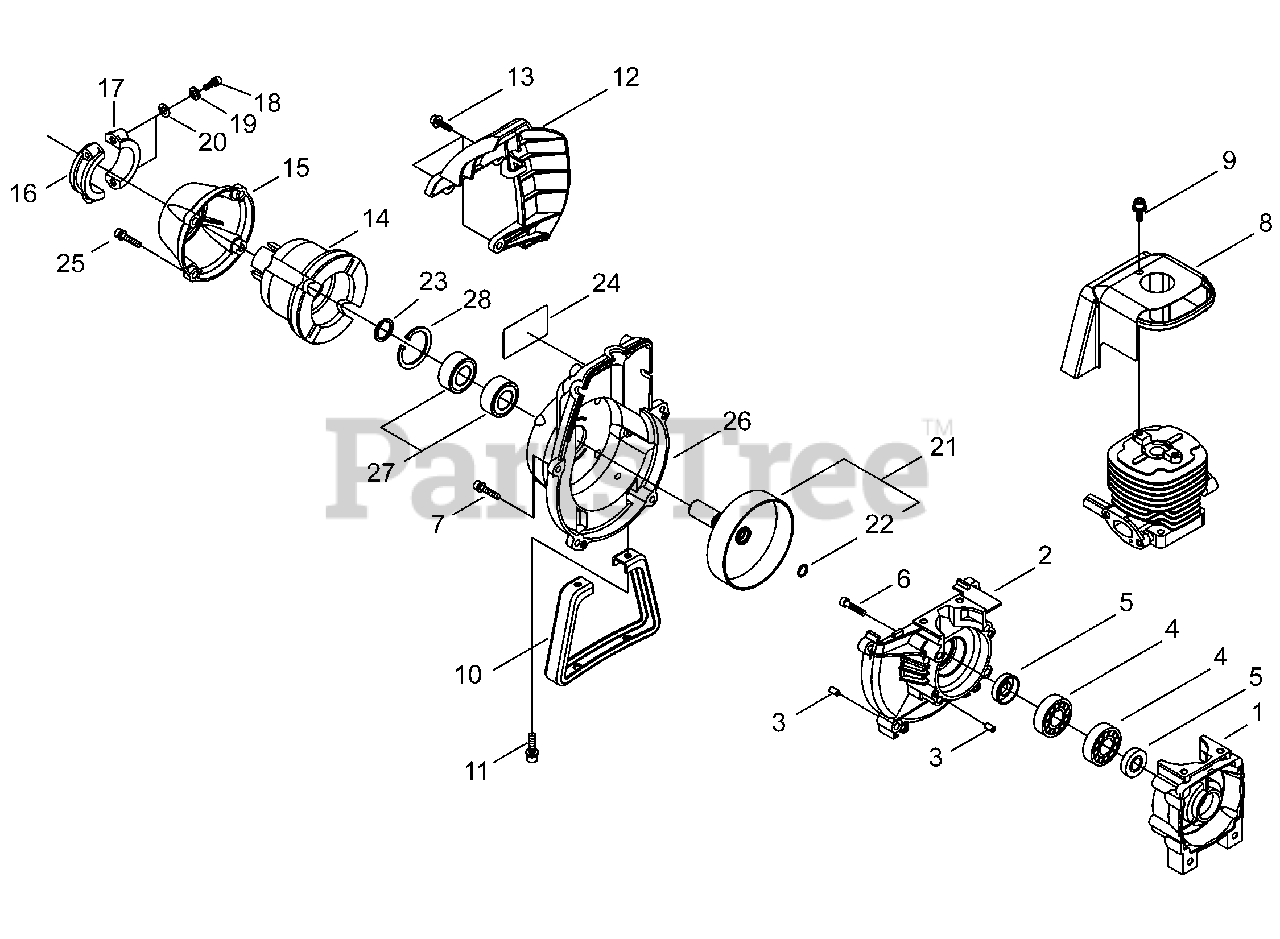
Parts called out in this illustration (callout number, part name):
1	CRANKCASE S
2	CRANKCASE M
3	PIN, LOCATING 5×10
4	BEARING, BALL 6202 C3
5	SEAL, OIL 16
6	BOLT 5×30
7	BOLT M5×20
8	COVER, ENGINE
9	BOLT 5×14
10	STAND
11	BOLT M5×16
12	GUARD, TOP
13	BOLT M4×16
14	CUSHION, AV
15	CAP, CUSHION
16	CLAMP (A)
17	CLAMP (B)
18	BOLT 5×25
19	WASHER, SPRING 5
20	WASHER, FLAT 5.5×10×0.8
21	DRUM, CLUTCH
22	RING, RETAINING
23	RING, SNAP
24	LABEL, TRADE
25	BOLT M5×20
26	COVER, FAN
27	BEARING, BALL 6002 DDU
28	RING, SNAP Ø32
